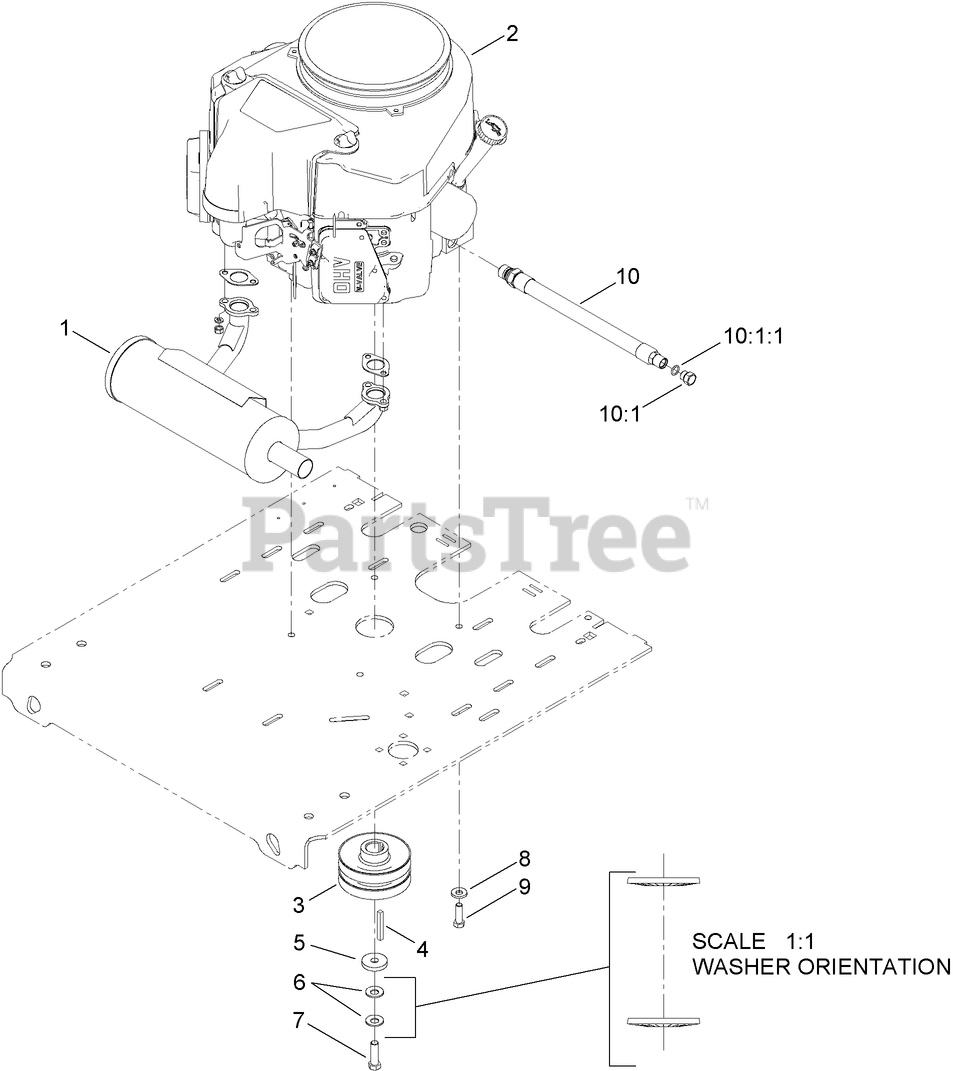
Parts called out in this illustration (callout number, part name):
1	MUFFLER-HORIZONTAL
3	PULLEY
5	WASHER-CLUTCH
6	WASHER-SPRING
7	SCREW-HH, W/LOCTITE
8	WASHER-BELLEVILLE
9	SCREW-HH
10	ENGINE OIL DRAIN HOSE ASM
10:1	PLUG-HH
10:1:1	O-RING
